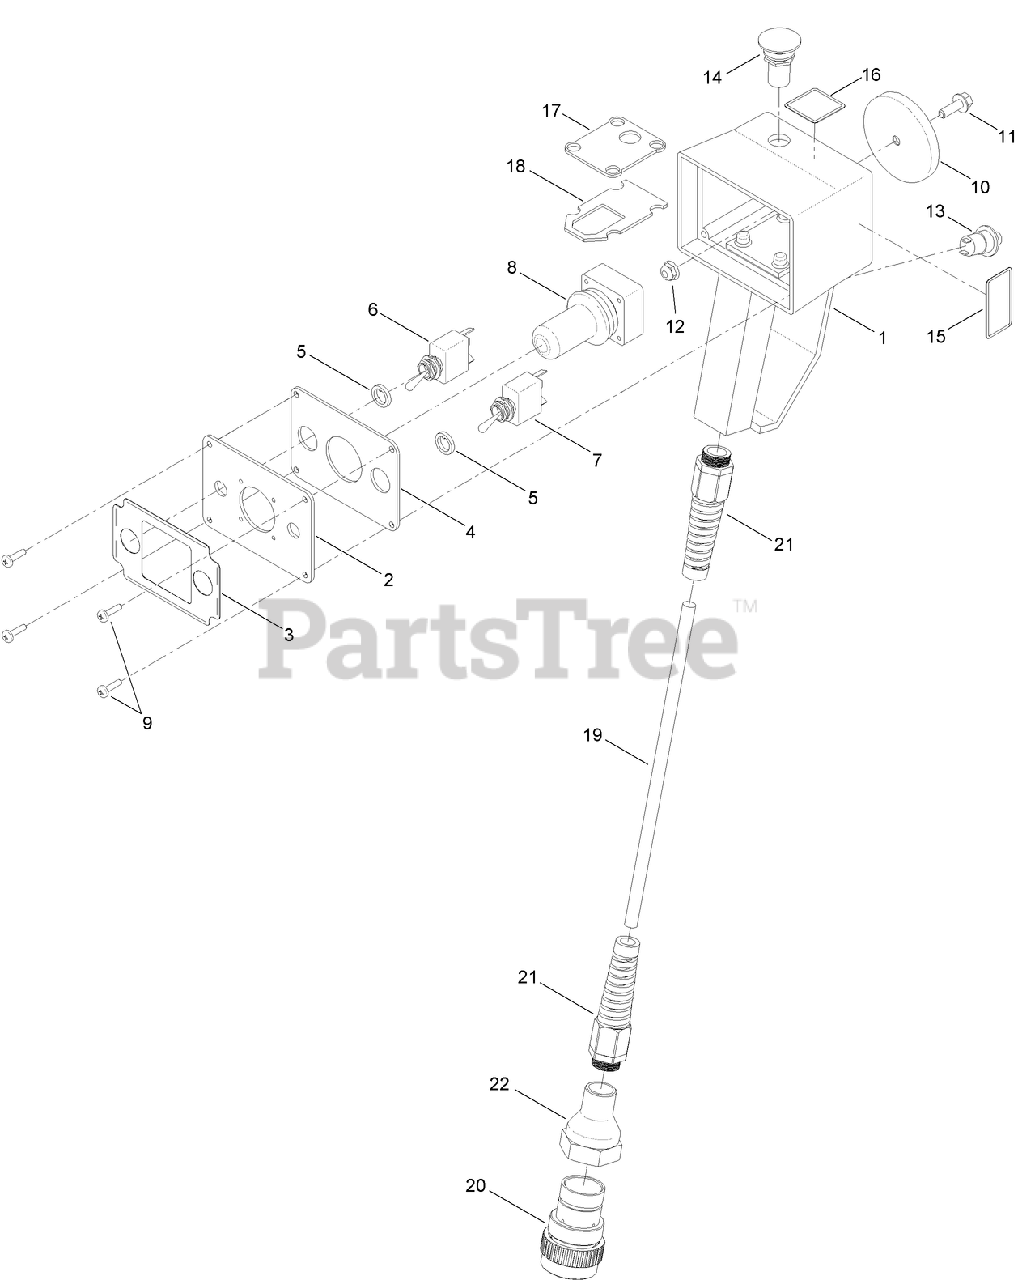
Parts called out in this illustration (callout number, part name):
1	ENCLOSURE-HANDHELD
2	PLATE-JOYSTICK
3	DECAL-TRAVEL PENDANT
4	GASKET-ENCLOSURE
5	SEAL-SWITCH
6	SWITCH
7	SWITCH
8	JOYSTICK
9	SCREW-PPH
10	MAGNET-CERAMIC, ENCASED
11	SCREW-HHF
12	NUT-HF
13	SWITCH-MOMENTARY
14	SWITCH-PUSH BUTTON
15	DECAL-OPERATOR PRESENCE
16	DECAL-EMERGENCY STOP
17	GASKET-HANDLE, INNER
18	GASKET-HANDLE, OUTTER
19	CABLE-TRAVEL PENDANT
20	PLUG-CONNETOR
21	GRIP-CORD
22	COUPLER
